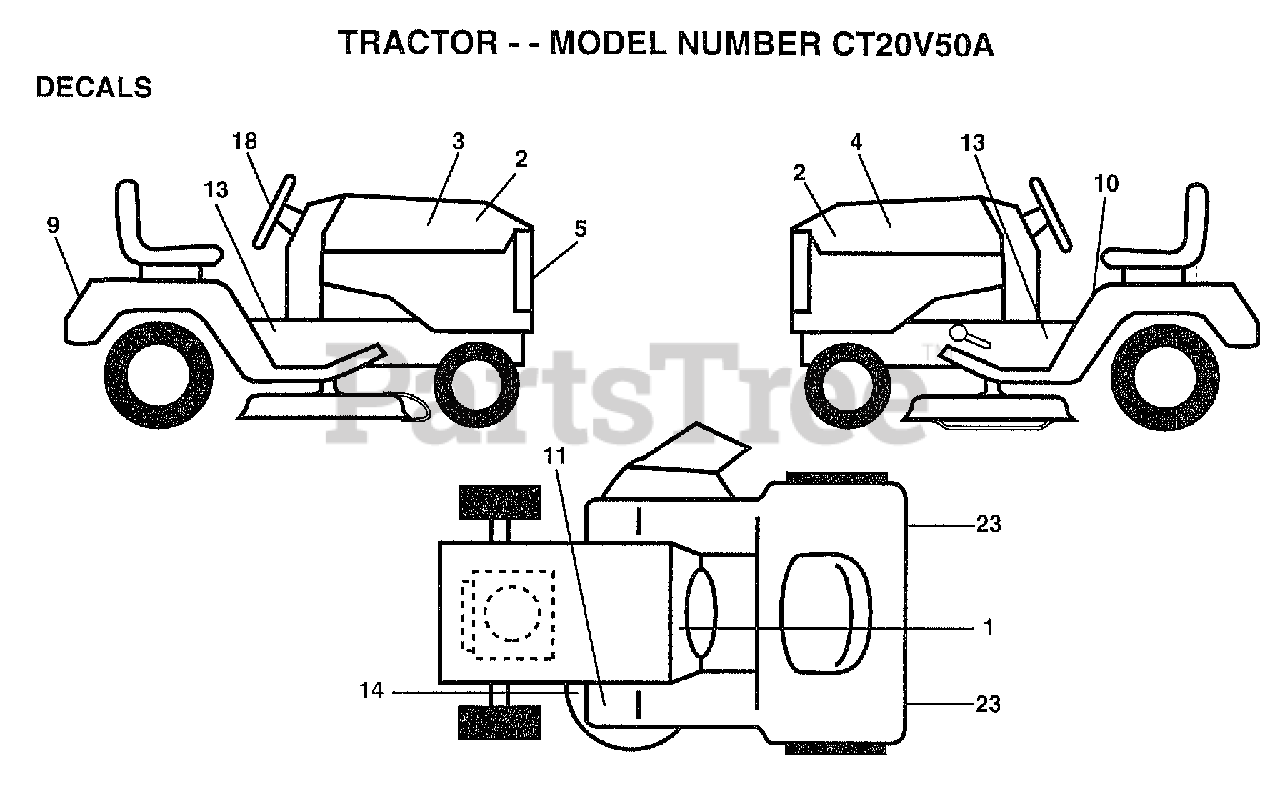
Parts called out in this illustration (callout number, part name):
1	DECAL.DASH.INST.
2	DECAL.HOOD.INS
3	DECAL.HOOD.RH.
4	DECAL.HOOD.LH.
5	DECAL.GRILLE
9	DECAL.FENDER
10	DECAL
13	DECAL.CHASSIS 6SP
14	"DECAL.V.BELT.44"""
18	DECAL INST STRWHL
23	REFLECTOR-TAIL YT
